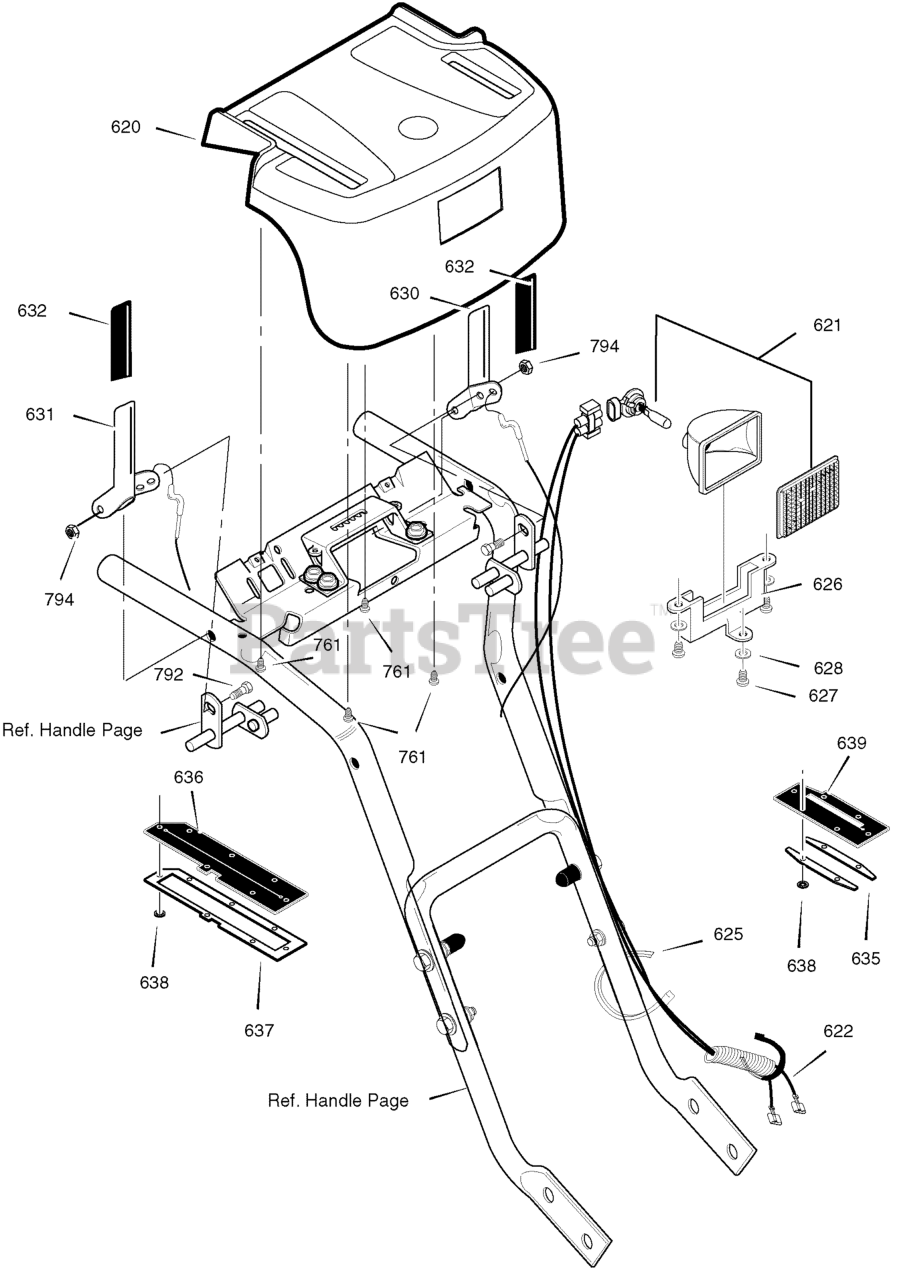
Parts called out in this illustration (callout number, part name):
620	PANEL, CONTROL W/LIGHT
621	LIGHT, HALOGEN
622	HARNESS, WIRE
625	TIE, CABLE
626	BRACKET, LIGHT
627	SCREW #8 X .50
628	WASHER, FLAT
630	CLUTCH HANDLE LH
631	CLUTCH HANDLE RH
632	GRIP, CLUTCH LEVER
635	FRAME, COVER
636	COVER, SPEED LEVER
637	FRAME, SPEED COVER
638	NUT, PUSH
639	COVER, CHUTE LEVER
792	BOLT, 1/4-20 X 0.50
794	NUT, 1/4-20
